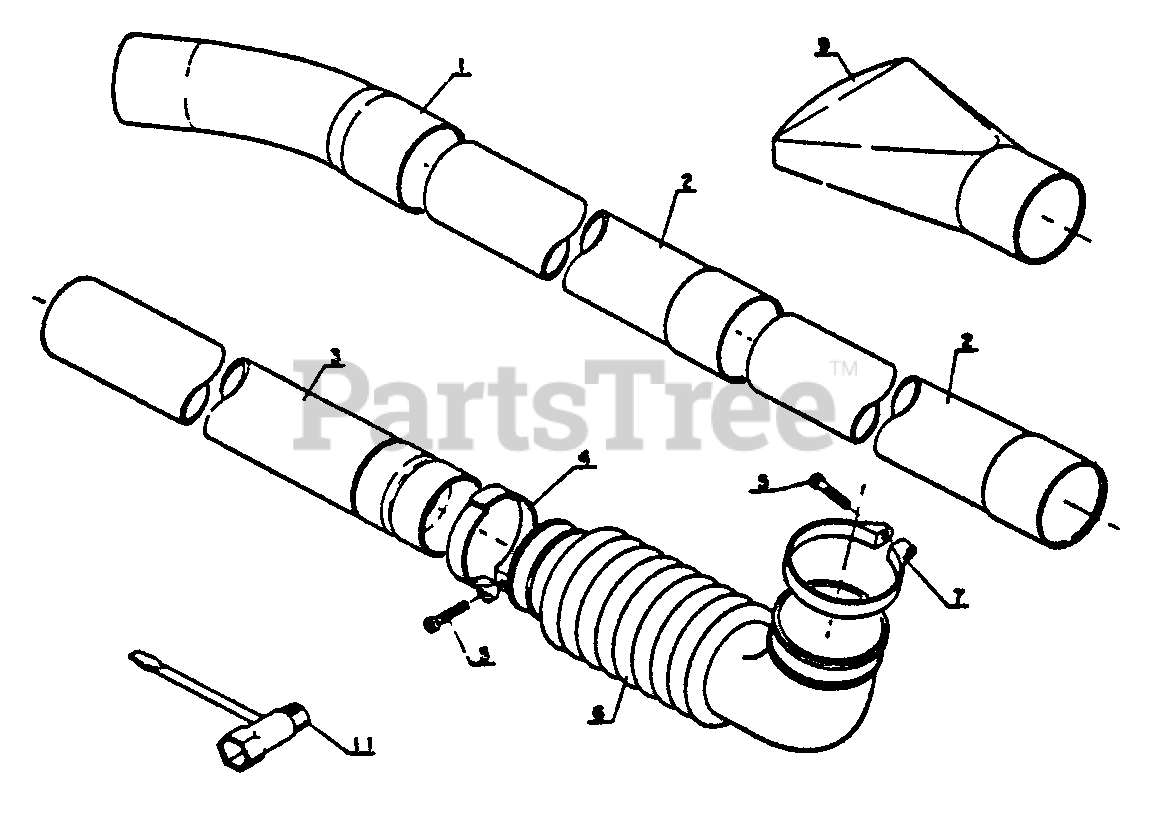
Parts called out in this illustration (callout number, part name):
1	TUBE, BLOWER - CURVED
2	TUBE, BLOWER - STRAIGHT
3	TUBE, BLOWER - STRAIGHT
4	CLAMP
5	SCREW 5×25
6	TUBE, BLOWER - FLEXIBLE
7	CLAMP
9	NOZZLE - FAN HEAD
11	T-WRENCH 13×19×180
